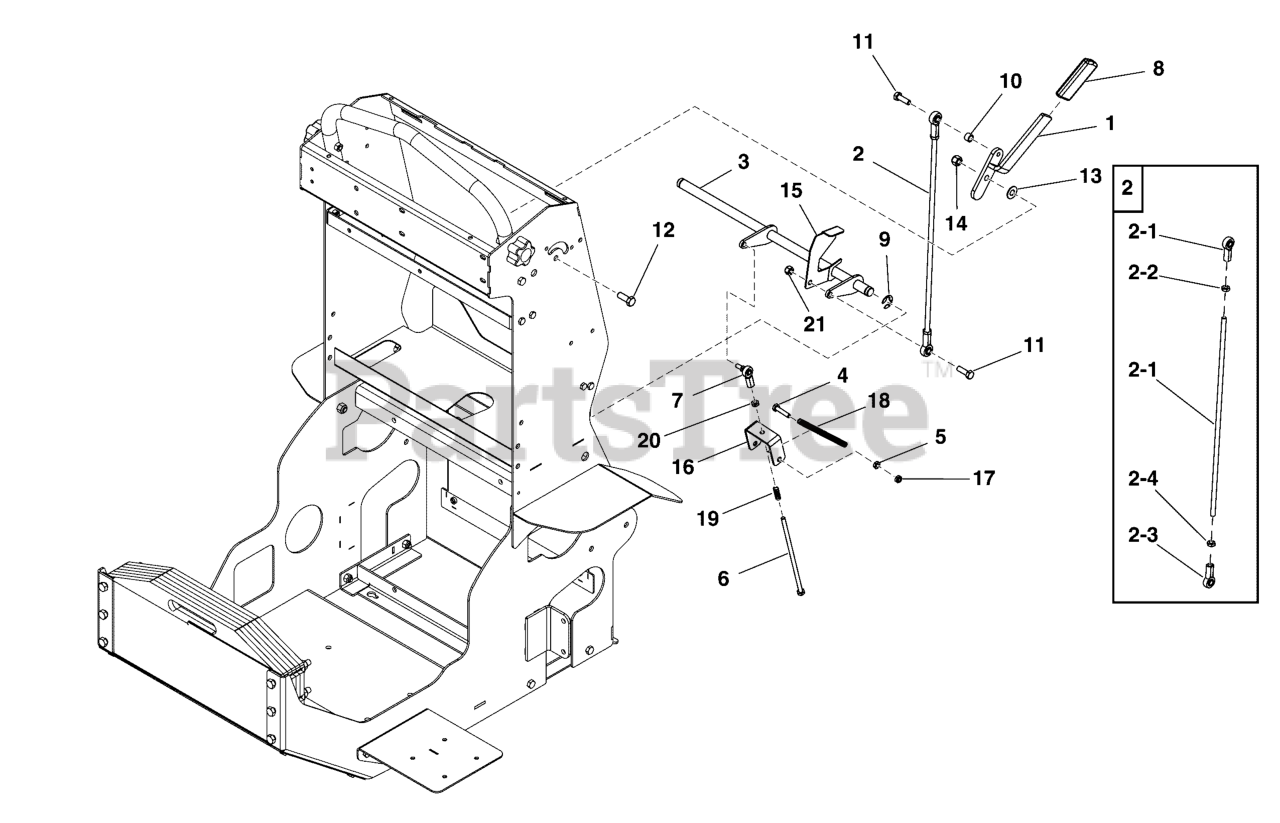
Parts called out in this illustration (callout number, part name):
1	WELD, PARK BRAKE HANDLE
2	ASM, PARK BRAKE ROD
2-1	ROD, CONTROL 5/16-24 THD X 16.50" MZ
2-2	ROD END, FEMALE 5/16-24 LH ZP PTFE RACE
2-3	ROD END, FEMALE 5/16-24 RH ZP PTFE RACE
2-4	NUT-HEX, JAM .3125"-24 SS188
3	WELD, PARK BRAKE SHAFT ASSEMBLY
4	SCR-CAP, HEX .250"-20 X 1.250" SS188
5	NUT-HEX, JAM .250"-20 SS188
6	SCR-CAP, HEX .250"-28 X 7.000" G5 ZP
7	ROD END, 1/4-28 WITH STUD
8	GRIP, .188" X 1.00" ID X .150" THK CLSD CELL FOAM
9	E-RING, 0.625" SHAFT YZ
10	SPCR-SS, 304 0.375" X 0.500" X .357"
11	SCR-CAP, HEX .3125"-18 X 1.000" SS188
12	SCR-CAP, HEX .375"-16 X 1.000" SS188
13	WSHR-STL, FLT .406" X .875" X .050" IS SS188
14	NUT-HEX-NYLK, .375"-16 SS188
15	PLATE, CONTACT, PARKING BRAKE SWITCH
16	BRACKET, LINKAGE PARK BRAKE
17	NUT-HEX-NYLK, .250"-20 TH SS188
18	SPRING, EXTENSION .64" OD X 4.00" LG SS
19	SPRING, COMPRESSION .36 OD X 1.00 LG SS
20	NUT-HEX, JAM .250"-28 SS188
21	NUT-HEX-NYLK, 0.3125"-18 SS188
